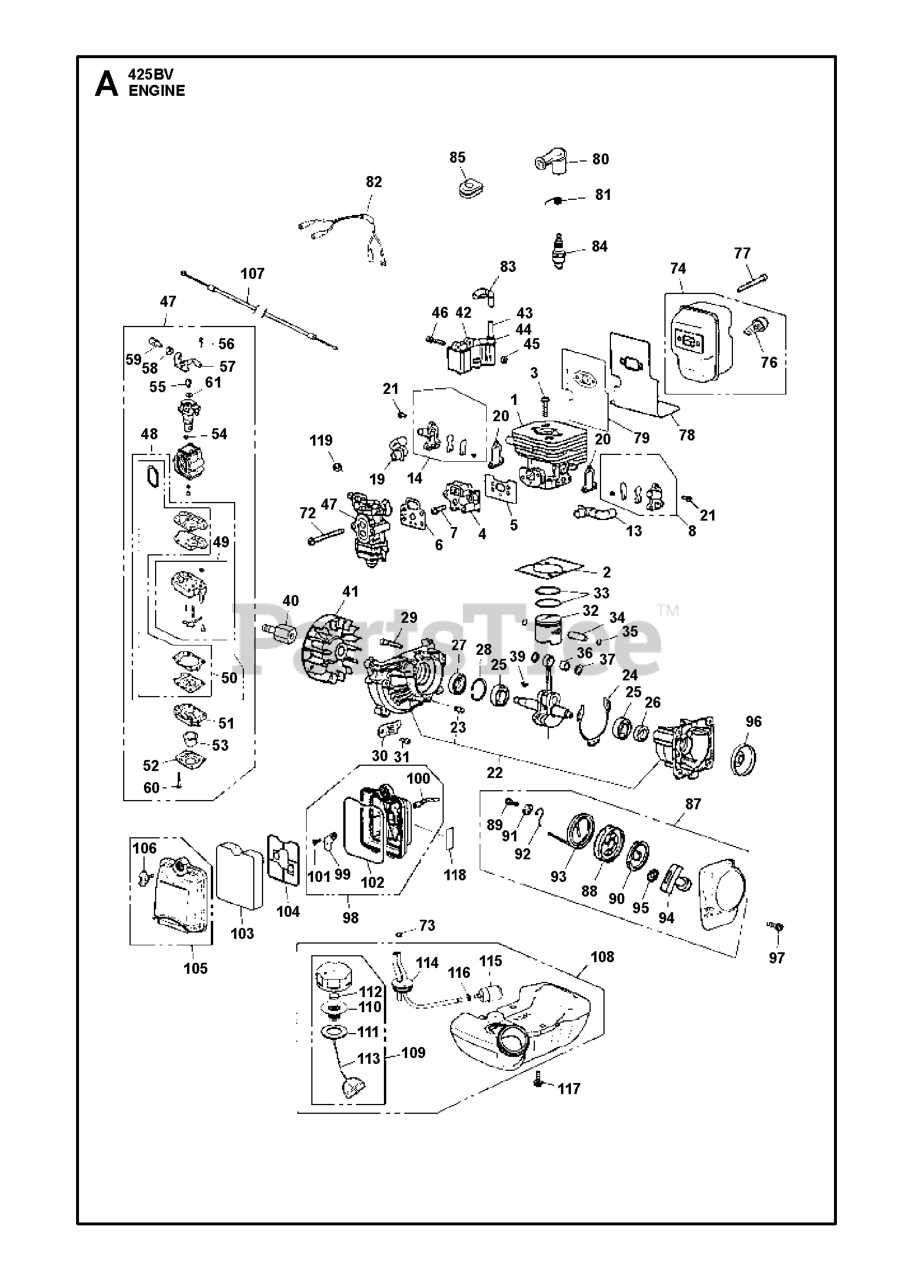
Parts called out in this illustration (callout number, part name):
2	GASKET, BASE
5	GASKET.INSU
7	BOLT
8	REEDVALVE(S)-A
13	PIPE AIR (S)
14	REEDVALVE(F)-A
19	PIPE AIR (F)
20	GASKET, VALVE
22	CRANKCASE-C
23	PIN
24	GASKET.CASE
25	BEARING
31	BOLT 08
34	PIN (RPLS T151341310)
36	BEARING (R550041410&114041330)
38	CRANKSHAFT COMP(RPLS481042000)
40	EXTENSION.
43	CORD (BLACK)
44	CAP
47	CARBURETOR-A
48	REBUILD KIT
49	CARBURETOR BODY
50	GASKET KIT
51	BODY
52	1OVER
53	PUMP
54	RING
55	SWIVEL
56	SCREW
57	BRACKET
58	NUT
60	SCREW
61	WASHER
76	ARRESTER
78	GASKET, MUFFLER
79	PLATE, MUFFLER
84	PLUG CMR7H
85	GROMMET
88	REEL
89	SCREW
90	SPRING, SPIRAL
91	COLLAR
92	SWING ARM
93	ROPE
94	KNOB
95	PLATE.STOPPER
99	PLATE.CHOKE
100	LEVER CHOKE
101	SCREW
102	PACKING
105	COVER ASSY
106	KNOB
109	CAP A
110	HOLDER-A
111	PACKING
112	FILTER
113	STOPPER
114	PIPE-C
115	FILTER
116	CLIP
118	LABEL, CHOKE
